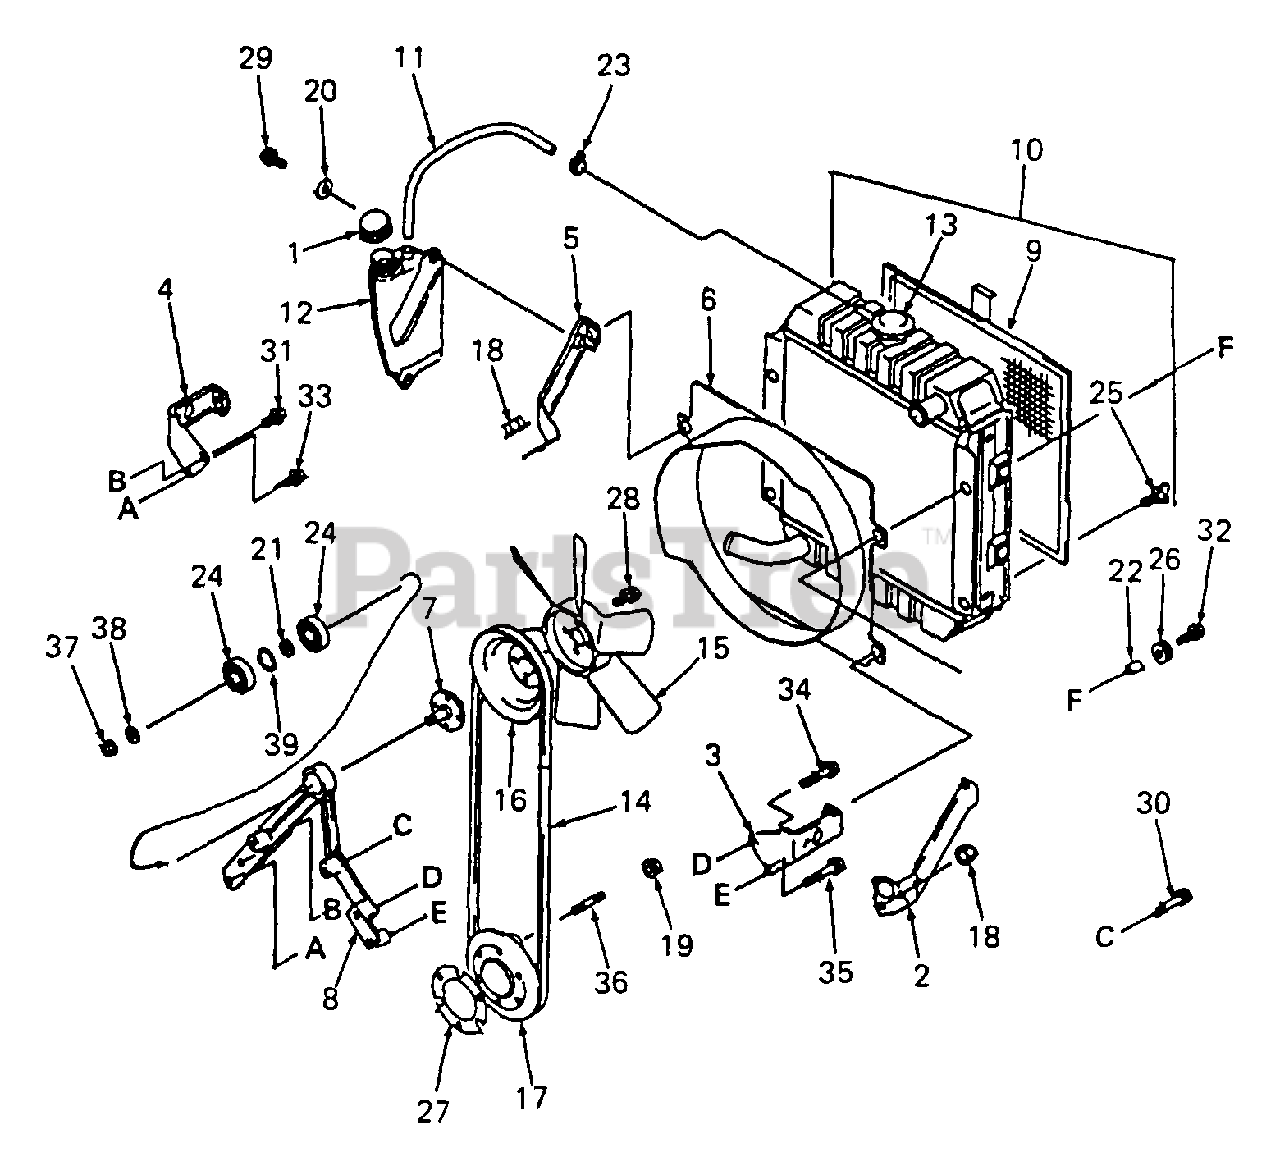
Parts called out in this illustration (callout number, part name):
1	Cap, Overflow Tank
2	Bracket
3	Bracket
4	Bracket
5	Bracket
7	Shaft, Pulley
8	Housing Assy
9	Screen, Radiator
10	Radiator Assy
11	Hose, Overflow Return, 7.5 x 10.5 x 460
12	Tank, Overflow
13	Cap, Radiator Pressure
16	Pulley
21	Spacer, 12 x 18 x 1.4
24	Bearing, Ball
27	Shim, T = 0.6
28	Bolt, Flanged, 6 x 16
29	Bolt, Flanged, 6 x 18
30	Bolt, Flanged, 6 x 35
31	Bolt, Flanged, 8 x 20
32	Bolt, Flanged, 8 x 25
33	Bolt, Flanged, 8 x 30
34	Bolt, Flanged, 8 x 40
35	Bolt, Flanged, 8 x 45
36	Bolt, Stud, 8 x 18
37	Nut, 10 MM
38	Washer, Plain, 10 MM
39	Circlip, 28 MM
